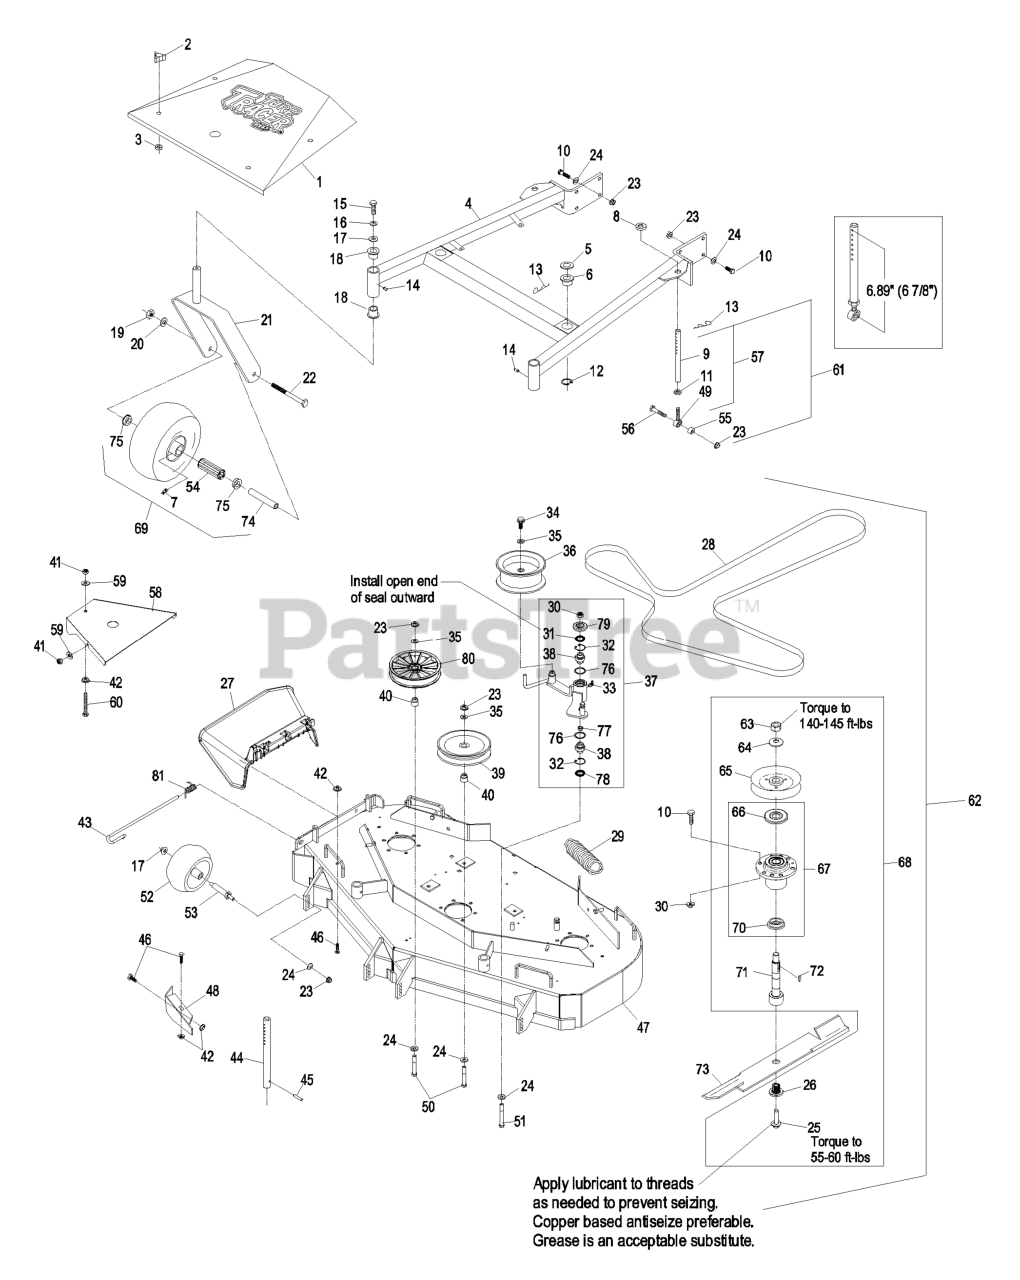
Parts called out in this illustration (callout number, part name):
2	KNOB-3 PRONG
4	DECK SUPPORT W/BSHGS 48"
5	SPACER-DECK SUPPORT
6	BUSHING-DECK
7	FITTING-GREASE
9	LINK,SUPPORT
10	SCREW-HH
11	NUT-HJ
12	RING-RETAINING
13	PIN,HAIR COTTER
14	FITTING-GREASE
15	SCREW-HH
16	WASHER-LOCK
17	Nut-Nyloc 3/8-16 Flg
18	BEARING-FLANGED
19	NUT-HH
20	WASHER-LOCK
22	SCREW-HH
23	NUT-HHF, WHIZ
24	WASHER-BELLEVILLE
25	SCREW,SEMS 1/2-20 X 2.19
26	BUSHING,SPLINED
27	CHUTE DEFLECTOR XRK M056
28	BELT - V, B
30	NUT-LOCK, NI
31	SEAL-LIP, SINGLE
32	RING-SNAP
33	FITTING-GREASE, 90 DEG
34	SCREW-HHF
35	WASHER-FLAT
37	KIT, DECK IDLER TTHP48&52
38	BEARING-SPHERICAL
39	PULLEY-IDLER
40	BUSHING-IDLER
41	NUT-LOCK, NI
43	PIN-CHUTE
44	ROD,DECK SUPPORT
46	SCREW-HH
47	ASM,DECK W/DECALS TTHP/MH
49	BALLJOINT
50	SCREW-HH
51	SCREW-HH
52	ROLLER-SCALP, ANTI
54	BEARING
56	SCREW-HH
58	SHIELD,BELT
59	WASHER-FLAT
60	BOLT,TAP HH
61	KIT,SUPPORT LINK W/PIN
62	Asm, Deck Complete
65	SHEAVE,W/HUB 5.72
66	GUARD-BEARING, TOP
67	KIT, CUTTER HOUSING
68	ASM, CUTTER HSG
69	KIT, SP CASTER WHEEL REPL
70	SPACER-GUARD, BOTTOM
71	KIT, SPLINED SPINDLE 103-
72	KEY-RECTANGLE
75	BUSHING
78	SEAL-LIP, DOUBLE
79	GUARD-TOP
80	PULLEY,IDLER 5"
81	SPRING, TORSION
